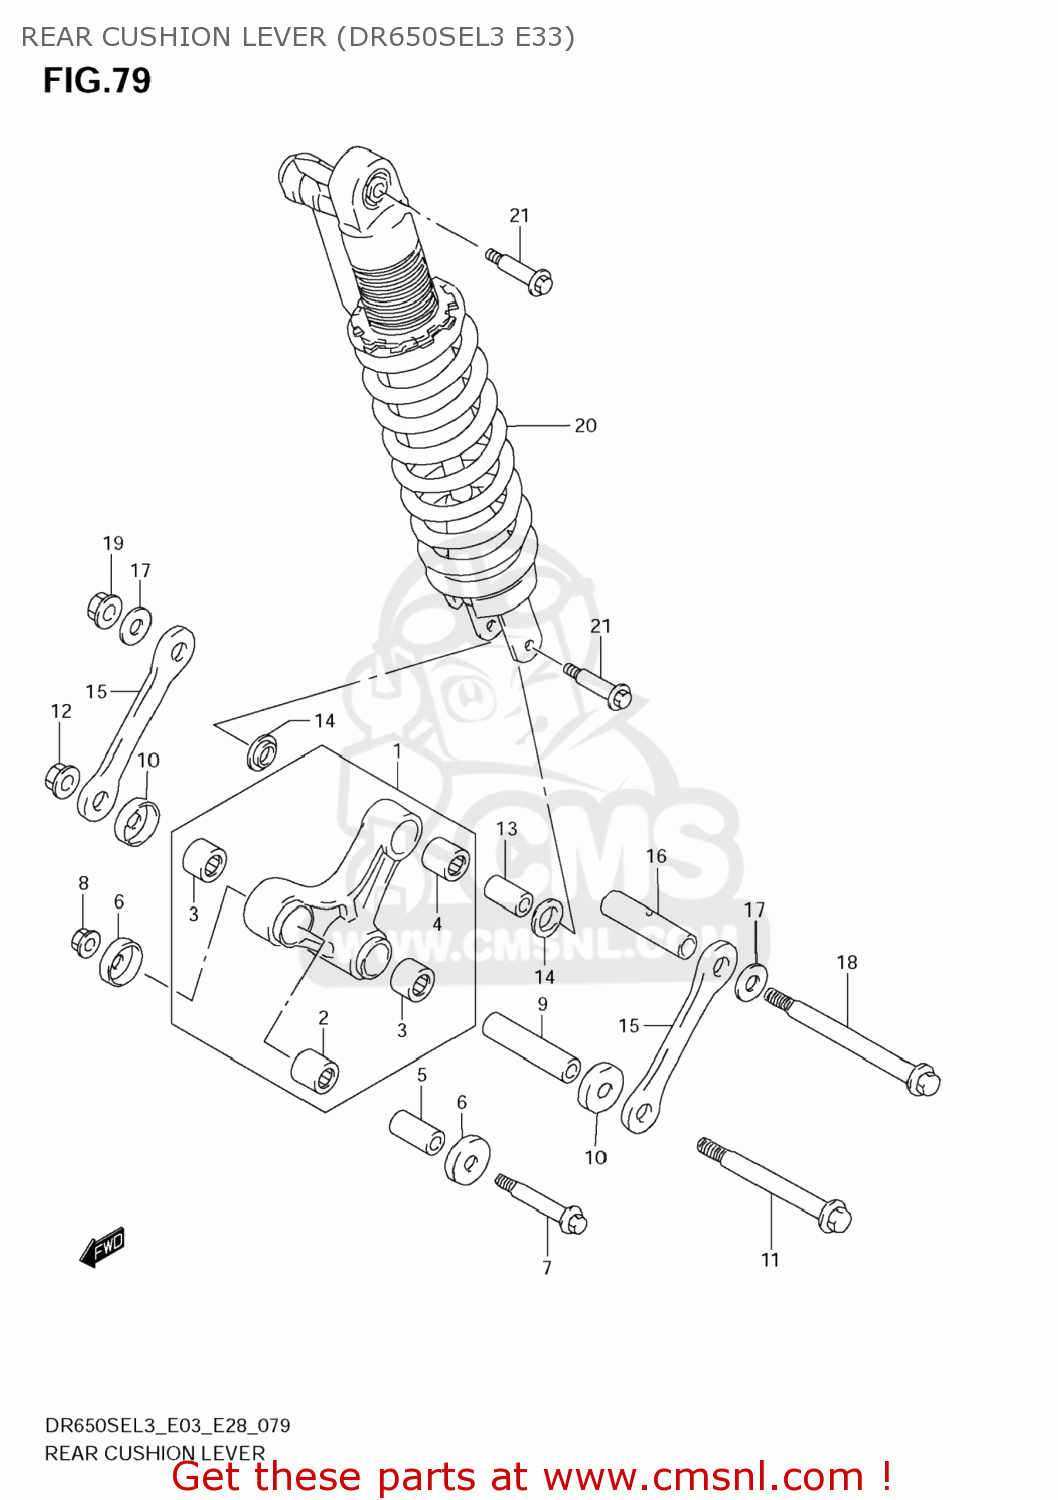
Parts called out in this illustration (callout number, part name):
1	LEVER SET,RR CUSHION
2	BEARING(20X27X30)
3	BEARING(21X27X20)
4	BEARING(17X24X20)
5	SPACER,RR CUSHION LEVER FR
6	SEAL,RR CUSHION LEVER FR DUST
7	BOLT,RR CUSHION LEVER FR
8	NUT
9	SPACER,RR CUSHION LEVER CTR
10	SEAL,RR CUSHION LEVER CTR
11	BOLT,RR CUSHION LEVER CTR
12	NUT
13	SPACER,RR CUSHION LEVER
14	SEAL,RR CUSHION LEVER RR DUST
15	ROD,RR CUSHION LEVER
16	SPACER,RR CUSHION LEVER CTR
17	WASHER
18	SHAFT,RR CUSHION LEVER FR
19	NUT
20	ABSORBER ASSY,RR SHOCK
21	BOLT,RR CUSHION ROD UPR
